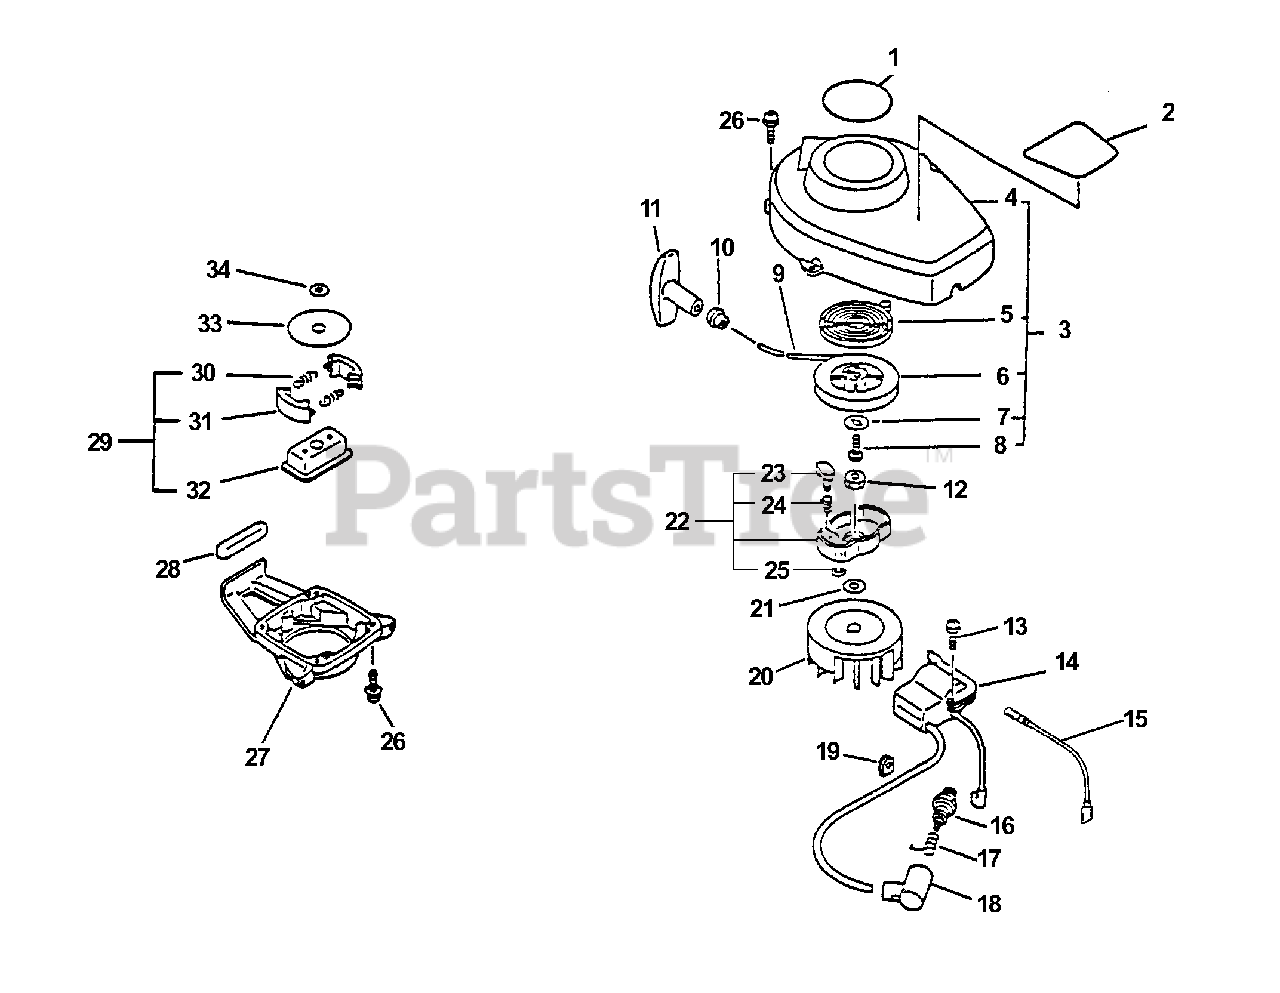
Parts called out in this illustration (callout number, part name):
1	LABEL - MODEL HC-2000
2	LABEL - CAUTION
3	STARTER ASSY
4	CASE, STARTER
5	SPRING, REWIND
6	REEL, ROPE
7	WASHER
9	ROPE, STARTER - 3.5X1000
10	GUIDE, ROPE
11	GRIP, STARTER
12	NUT - LEFT HAND
13	SCREW - 4X22
14	COIL, IGNITION
15	LEAD - IGNITION
16	SPARK PLUG -- BPM-7Y
16	SPARK PLUG -- RCJ-7Y
17	TERMINAL, SPARK PLUG CAP
18	CAP, SPARK PLUG
20	FLYWHEEL
21	WASHER - 8
22	STARTER PAWL ASSY
23	PAWL, STARTER
24	SPRING, RETURN
25	RING, RETAINING - 4
26	SCREW - 4X16
27	CASE, CLUTCH
28	CUSHION, FUEL TANK
29	CLUTCH ASSY
30	SPRING, CLUTCH
31	SHOE, CLUTCH
32	HUB, CLUTCH
33	PLATE, CLUTCH
34	WASHER, CLUTCH
